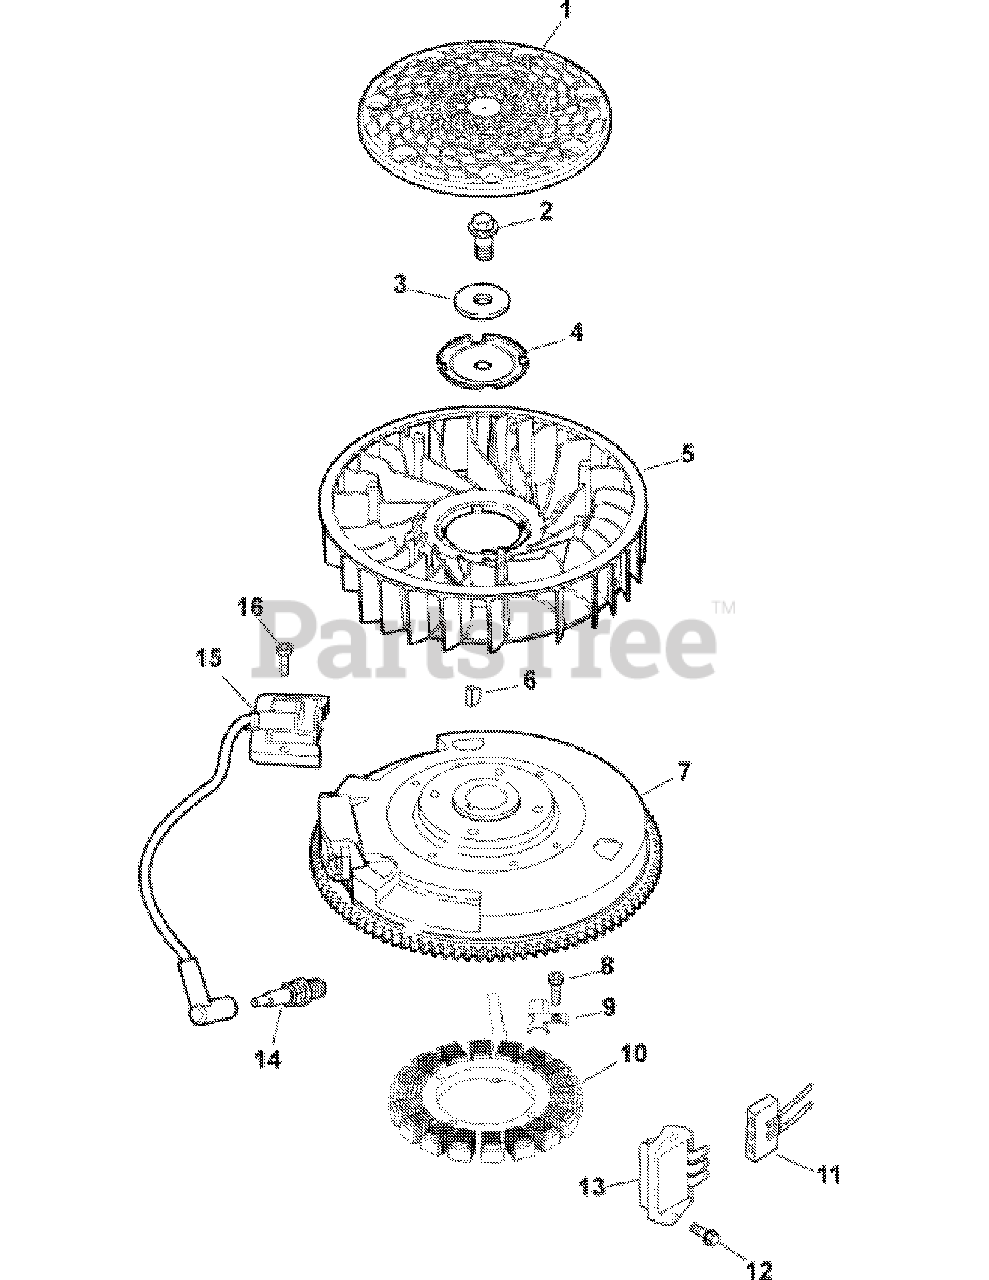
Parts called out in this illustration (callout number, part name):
2	SCREW, HEX FLANGE
3	WASHER, FLAT
4	PLATE, FAN MOUNTING
6	KEY, 3/16" X 5/8"
7	FLYWHEEL ASSEMBLY
8	SCREW, TRX HD DRIVE FASTENER - USE M-548025-S
10	KIT, 15 AMP STATOR
11	CONNECTOR (3 CONTACT)
12	SCREW, FLG THD FRM M5X.8X20
13	REGULATOR/RECTIFIER
14	PLUG, SPARK
15	MODULE, IGNITION (CDI FIXED)
16	SCREW, SCKT THRD FRM M5X0.8X25
